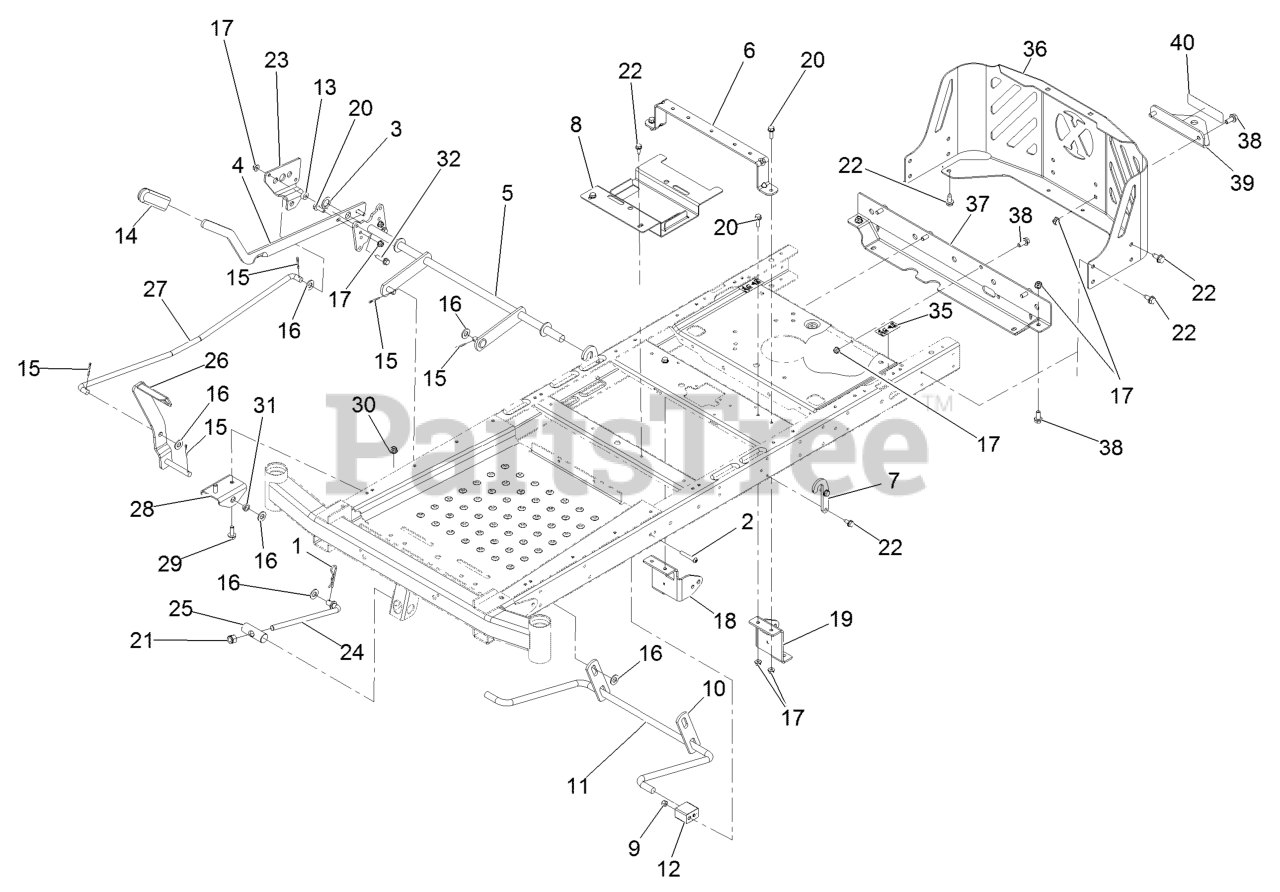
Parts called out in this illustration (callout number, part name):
1	PIN-COTTER
2	SCREW-HSBH
3	WASHER-THRUST
4	LEVER-LIFT
5	LIFT-DECK, WIDE
6	BRACE-SEAT, REAR
7	BRACKET-LIFT
8	BRACKET-BATTERY
9	NUT-LOCK, NI
10	LINK-LIFT
11	ARM-LIFT, REAR (WIDE)
12	BLOCK-PIVOT
14	GRIP-LEVER
15	PIN-COTTER
16	WASHER-FLAT
17	NUT-HF, NI
18	MOUNT-HYDRO, FRONT (RH)
19	MOUNT-HYDRO, FRONT (LH)
20	SCREW-HHF
21	NUT-HEX
22	Screw-HWH 5/16-18 X 3/4 Tf
23	PLATE-FOOTLIFT
24	ROD-MOUNT, DECK
25	PIN-PIVOT
26	PEDAL ASM
27	ROD-FOOTLIFT
28	BRACKET-FOOTLIFT
29	SCREW-HHF 3/8-16 X 1
30	NUT-HF, NI
31	BUSHING-FLANGE
32	SCREW-HHF
35	DECAL-BYPASS
36	GUARD-ENGINE, WIDE
37	CROSSMEMBER-REAR, WIDE
38	SCREW-HHF
39	BRACKET-HITCH
